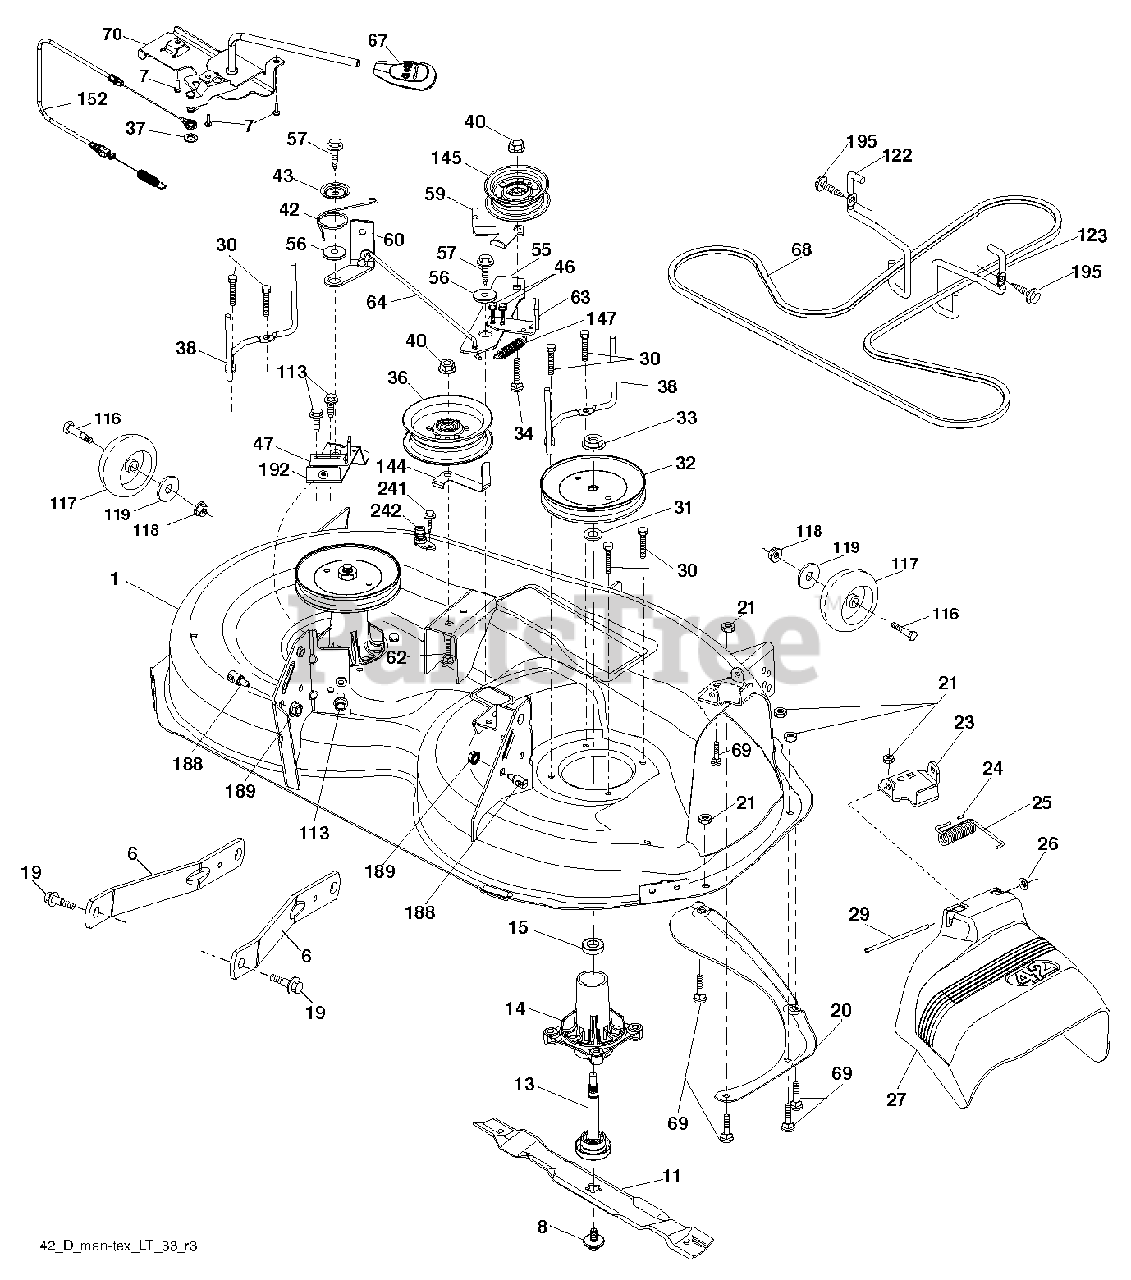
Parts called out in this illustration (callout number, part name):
1	DECK.WELDMENT.42"PAINT
6	ARM.SUSPENSION.MOWER.R
7	SCREW.#10 X 0.750.BOS
8	BOLT.WASHER.ASM.7/16-2
11	42" HI-LIFT BLADE
13	SHAFT.ASM.MDRL.N/GREASE.38
14	HOUSING.MANDREL.4PT.
19	BOLT.SHOULDER
20	BAFFLE.VORTEX
21	LOCKNUT
23	BRKT.DEFLECTOR.38"2005+
24	CAP-SLEEVE LT
25	SPRING.TORSION.DEFLECT
26	NUT PUSH M
27	SHIELD.DEFLECTOR.MOWER.42"BLAC
29	ROD.HINGE
30	SCREW, WASHER HEAD
31	WASHER.SPACER.MANDREL
32	PULLEY.MANDREL.5.438.PD
33	NUT.FLANGE.LOCK.TOP
34	BOLT.3/8-16X1.50
36	PULLEY.IDLER.2006
37	WASHER
38	KEEPER.BELT.LH.MANDREL
40	NUT LOCK FLG 3/8-16 UNC
42	SPRING.TORSION.BRAKE
43	SRPING.TORSION.RETAINE
46	SCREW.1/4-20X5/8
47	BRKT.CLUTCH.CABLE
55	IDLER.ARM.42"
56	SPACER.RETAINER
57	SCREW 3/8-16X1
59	GUARD, BELT
60	ARM BRAKE MOWER
63	ARM BRAKE MOWER
64	LINKAGE.BRAKE.ASM.ZINC
67	HANDLE.CLUTCH.CABLE.LT
68	BELT.DECK.DRIVE.42"
69	BOLT
70	CLUTCH.ASM.CABLE.HUSQ.TEX
113	BOLT.5/16HEX.WHS.HD
116	BOLT M
117	WHEEL.GAGE.HALF.SPOKED
118	NUT LOCK FLG 3/8-16 UNC
119	WASHER
122	KEEPER BELT ENGINE LH
123	KEEPER BELT RH
144	KEEPER.BELT.MOWER
145	PULLEY.IDLER.48"PRIMARY
147	RETURN SPRING
152	CABLE CLUTCH MANUAL W/SPR.
188	STUD.FASTNER.W/ANTI-ROTATE
189	NUT LOCK HEX FLANGE 5/16-18
192	BRKT.BRAKE.STAND.LH.
195	SCREW, 3/8-16X3/4
241	SCREW.TT.#10-32X.5.3/8.FLANGE
242	PORT.WASHOUT
